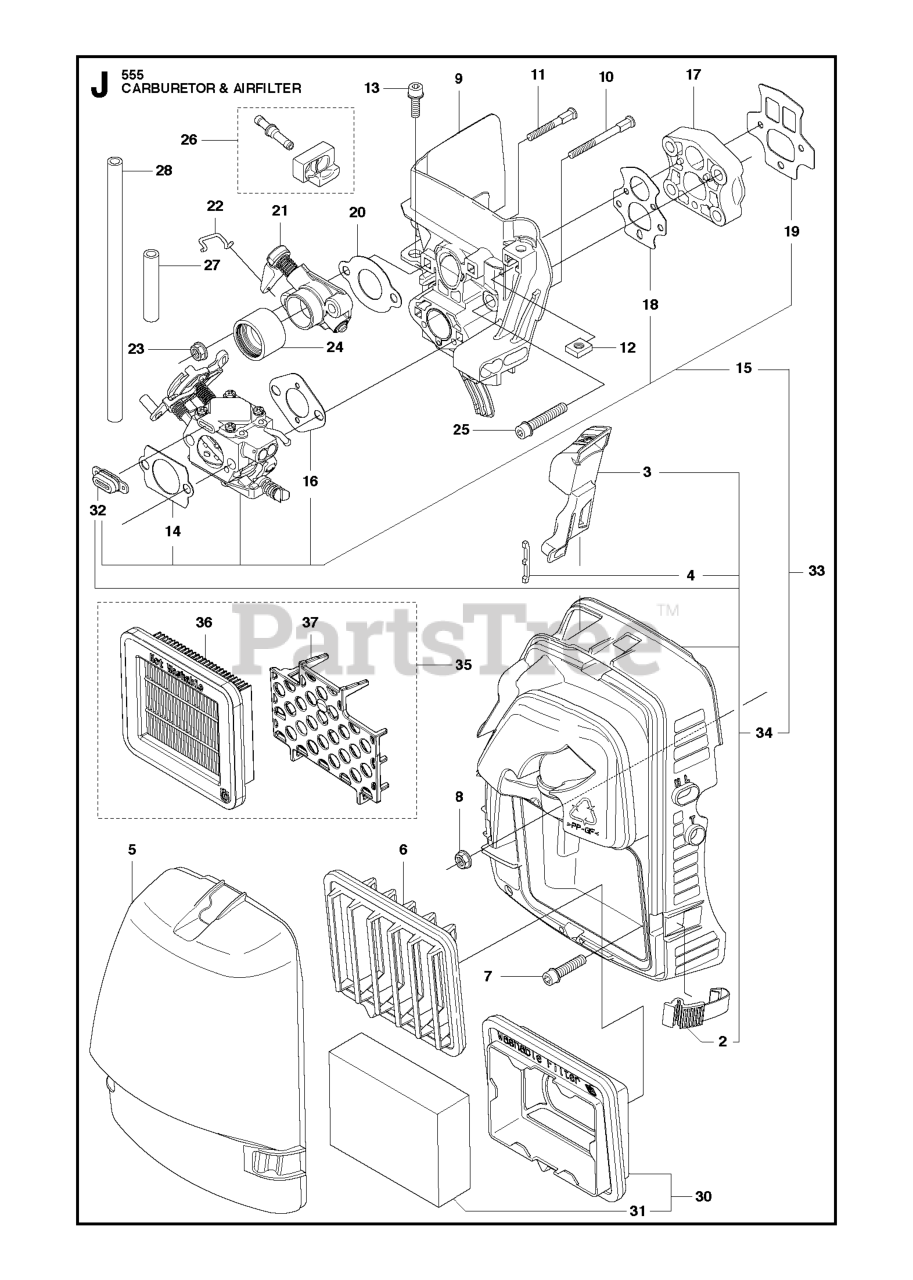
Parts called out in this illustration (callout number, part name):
3	CHOKE CONTROL
5	FILTER COVER
6	Filters
6	FILTER
9	INSULATION WALL
15	CARBURETOR
21	VALVE HOUSING
24	INLET PIPE
25	SCREW IHSCFM
26	GROMMET
27	FUEL HOSE STRAIGHT 35
28	RP FUEL HOSE
30	FILTER
31	FILTER
32	SEALING PLUG
33	CARBURETOR KIT
34	FILTER HOLDER KIT
36	FILTER AIR FILTER PAPER
